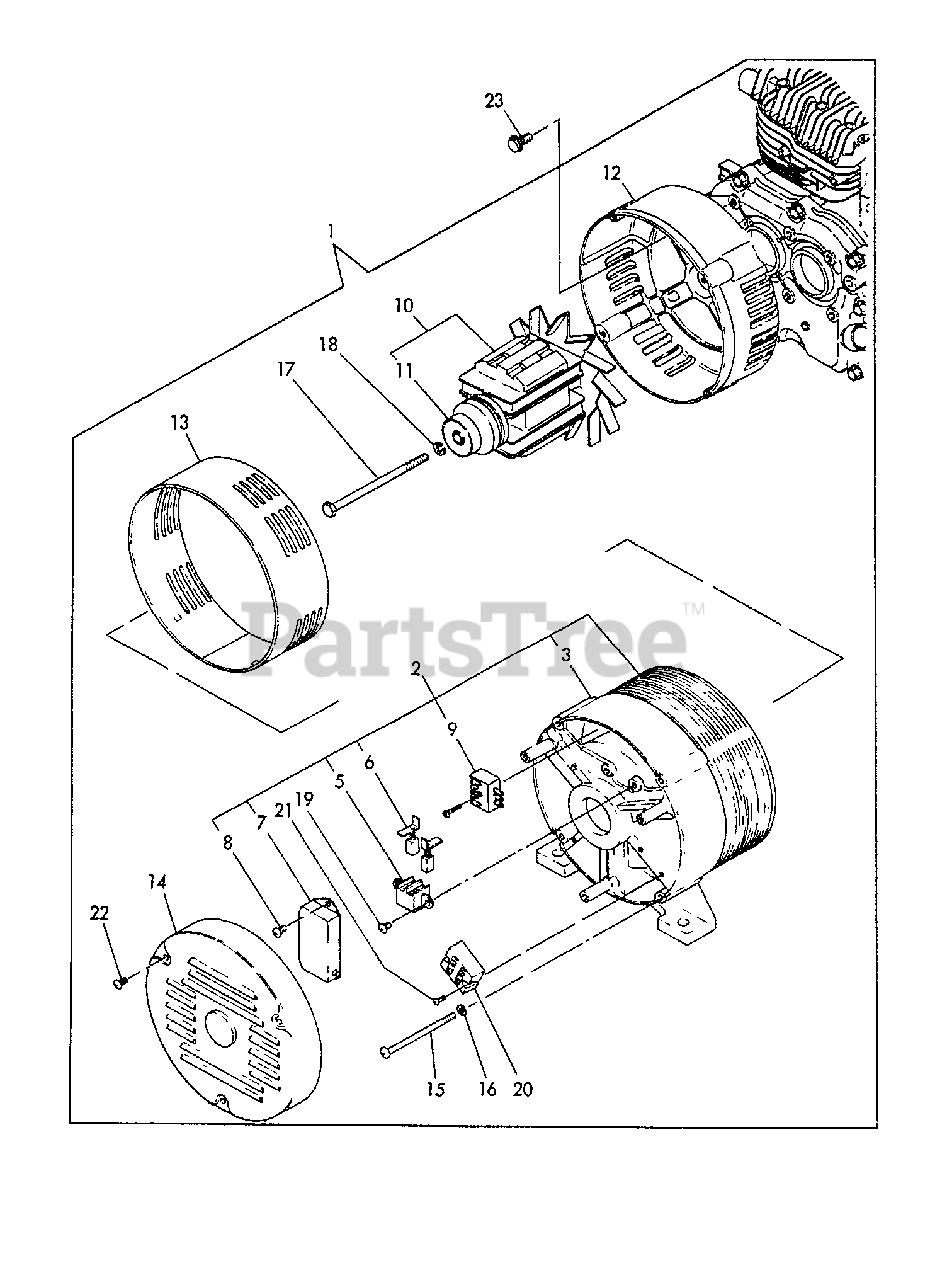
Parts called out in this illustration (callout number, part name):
1	GENERATOR 3.8KVA
2	STATOR ASSY
3	COVER - REAR
5	HOLDER, BRUSH
6	BRUSH ASSY
7	A.V.R.
8	SCREW - 4X14
9	RECTIFIER
10	ROTOR ASSY
11	BEARING, BALL
12	COVER - FRONT
13	CLAMP
14	COVER, END
15	BOLT, THROUGH
16	LOCKWASHER - 6
17	BOLT
18	LOCKWASHER - 10
19	SCREW - 5X14
20	TERMINAL
21	SCREW - 5X14
22	SCREW - 4X8
23	BOLT - 8X20 -- PLATED
